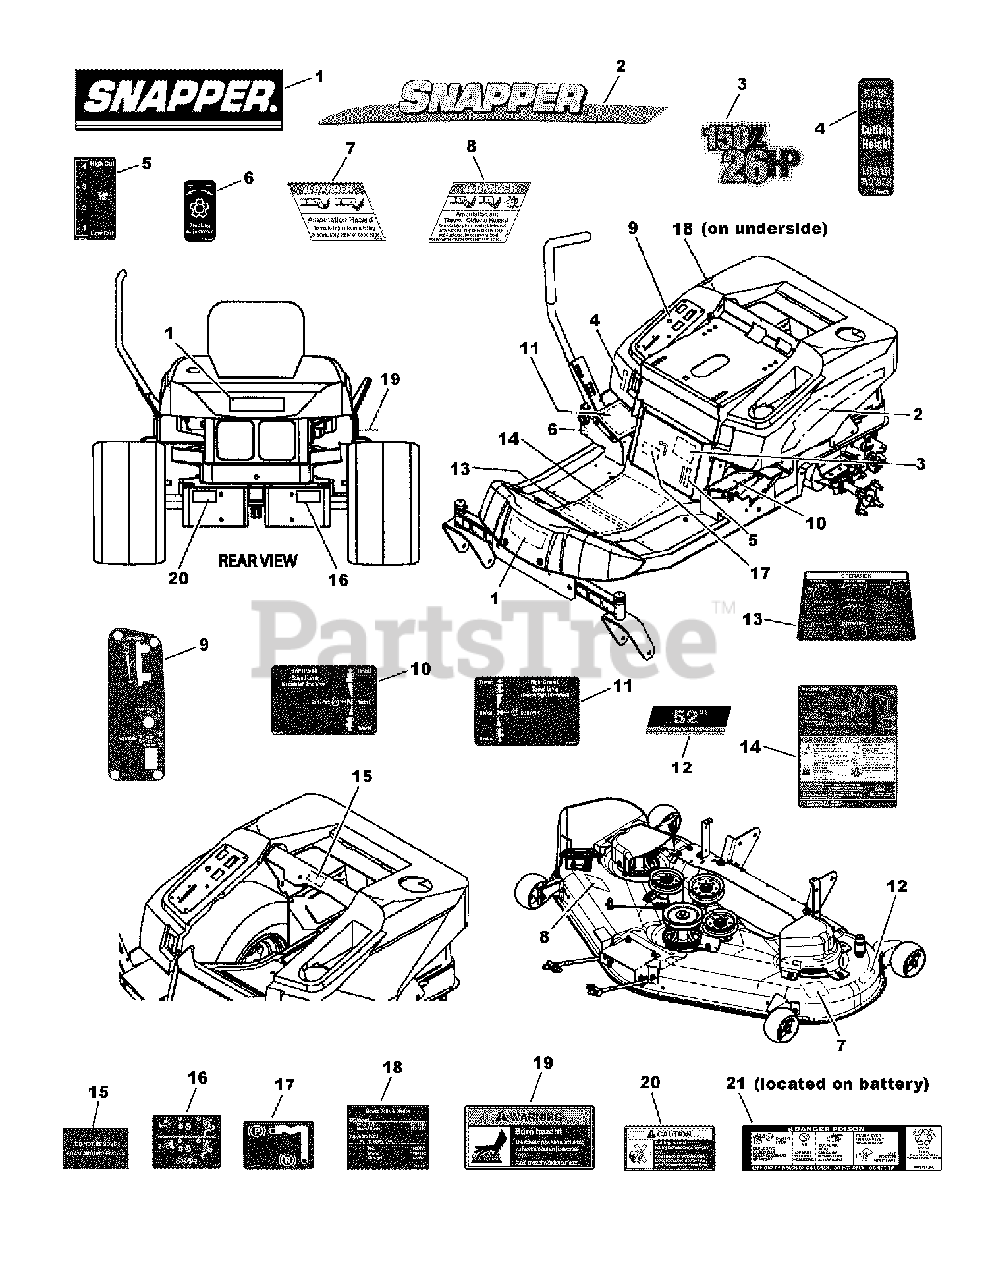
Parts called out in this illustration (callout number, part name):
1	DECAL, SNAPPER Logo
2	DECAL, New Snapper Stripe, LH
3	DECAL, 150Z 26HP SNAPPER ZT
4	DECAL, Mower Cutting Height ZTS 7500
5	DECAL, Height-Of-Cut
6	DECAL, Tracking Adjustment ZT 7000
7	DECAL, Danger- Do Not Put Hand/Feet in Mower
8	DECAL, Danger- Do Not Operate w/o Deflector
9	DECAL, Instrument Panel ZTS 7600
10	DECAL, LH Handle Control ZTS 7500
11	DECAL, RH Handle
12	DECAL, 52" Deck
13	DECAL, Handles Operation
14	DECAL, Operator Instructions
15	DECAL, Do Not Remove Foam Around Engine
16	DECAL, Transmission Release ZTS Export
17	DECAL, Parking Brake, ZT
18	DECAL, Belt/Blade ZT-52
19	DECAL, Warning, Burn Hazard
20	DECAL, Caution, Cut Hazard
21	DECAL, Danger Poison
